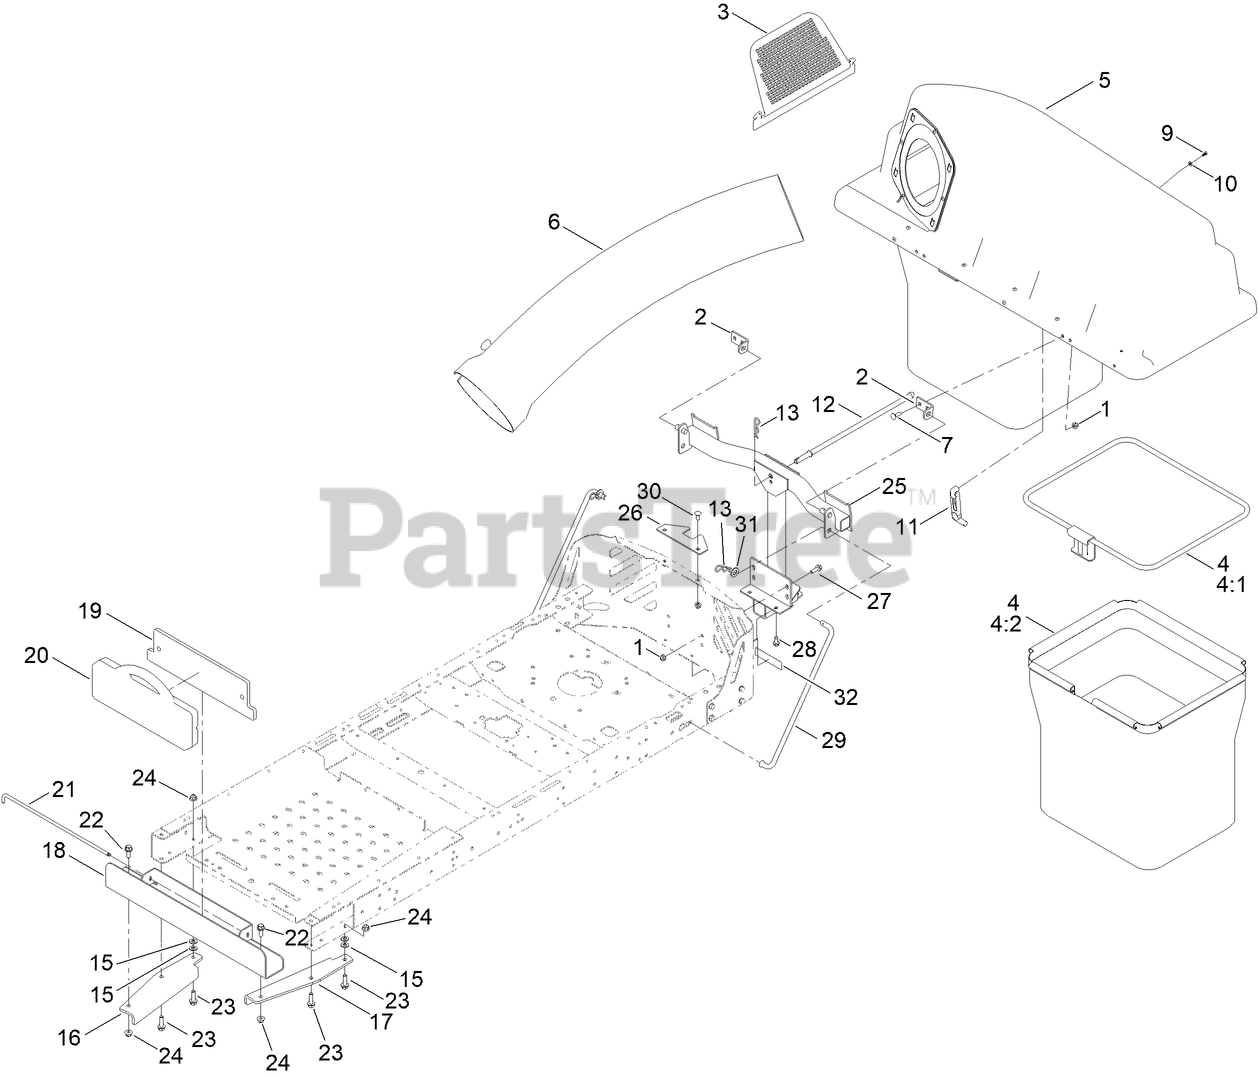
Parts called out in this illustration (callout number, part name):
1	NUT-HF, NI
2	BRACKET-PIVOT, HOPPER
3	SCREEN-BAGGER
4	BAG ASM
4:1	FRAME, BAG [BLACK]
4:2	BAG ASM 20IN DEPTH
5	BAGGER TOP ASM
6	TUBE-BAGGER
7	BOLT-CARR
9	SCREW-PLASTIC, PTH
10	WASHER-FLAT
11	LATCH-RUBBER
12	ROD-HOOD, DOWN (HOLD)
13	PIN-HAIR
15	WASHER-FLAT
16	BRACKET-BAGGER WEIGHT, RH
17	BRACKET-BAGGER WEIGHT, LH
18	CHANNEL-WEIGHT, BAGGER
20	WEIGHT-35 POUND
21	PIN-WEIGHT
22	SCREW-HHF
23	SCREW-HHF
24	NUT-HF, NI
25	FRAME ASM, PIVOT [BLACK]
26	BRACKET-STABILIZER
27	SCREW-HHF
28	SCREW-HWHTF
29	ROD-SUPPORT
30	BOLT-CARR
31	WASHER-FLAT
